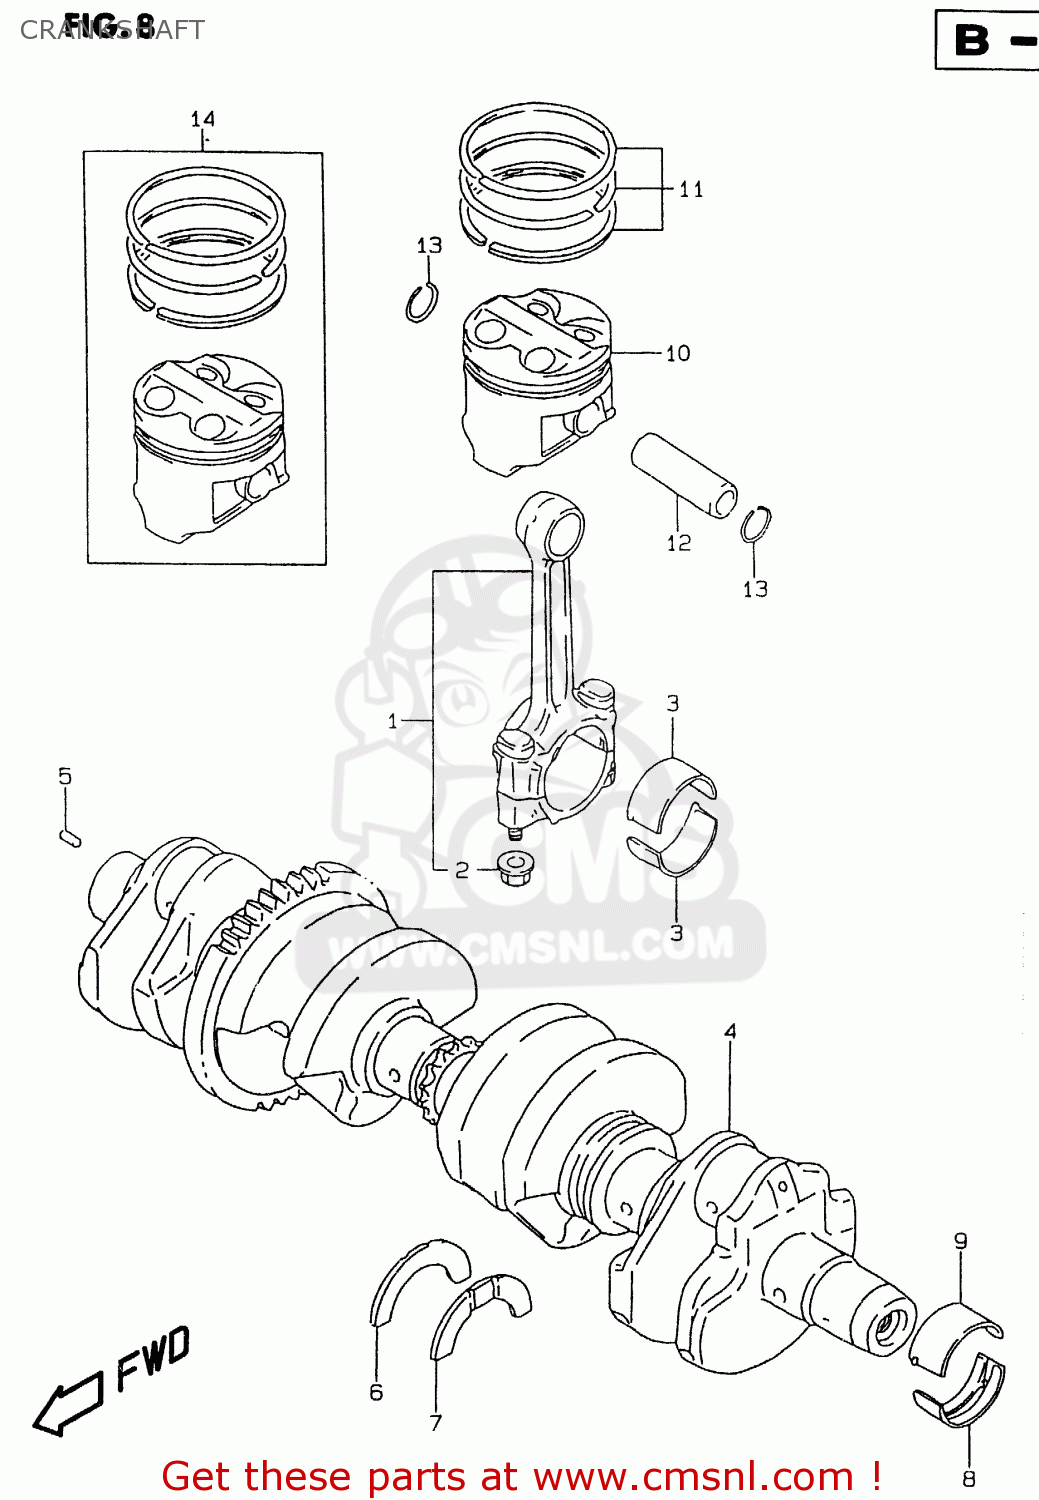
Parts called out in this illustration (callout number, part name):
1	ROD ASSEMBLY,CONNECTING
2	NUT
3	BEARING,CRANK PIN
4	CRANKSHAFT SET
5	PIN
6	PLATE,CRANK THRUST
7	PLATE,CRANK THRUST
8	BEARING,CRANKSHAFT LWR
9	BEARING,CRANKSHAFT UPR
10	PISTON
11	RING SET,PISTON
12	PIN,PISTON
13	CIRCLIP
14	PISTON SET(OS:0.5)
